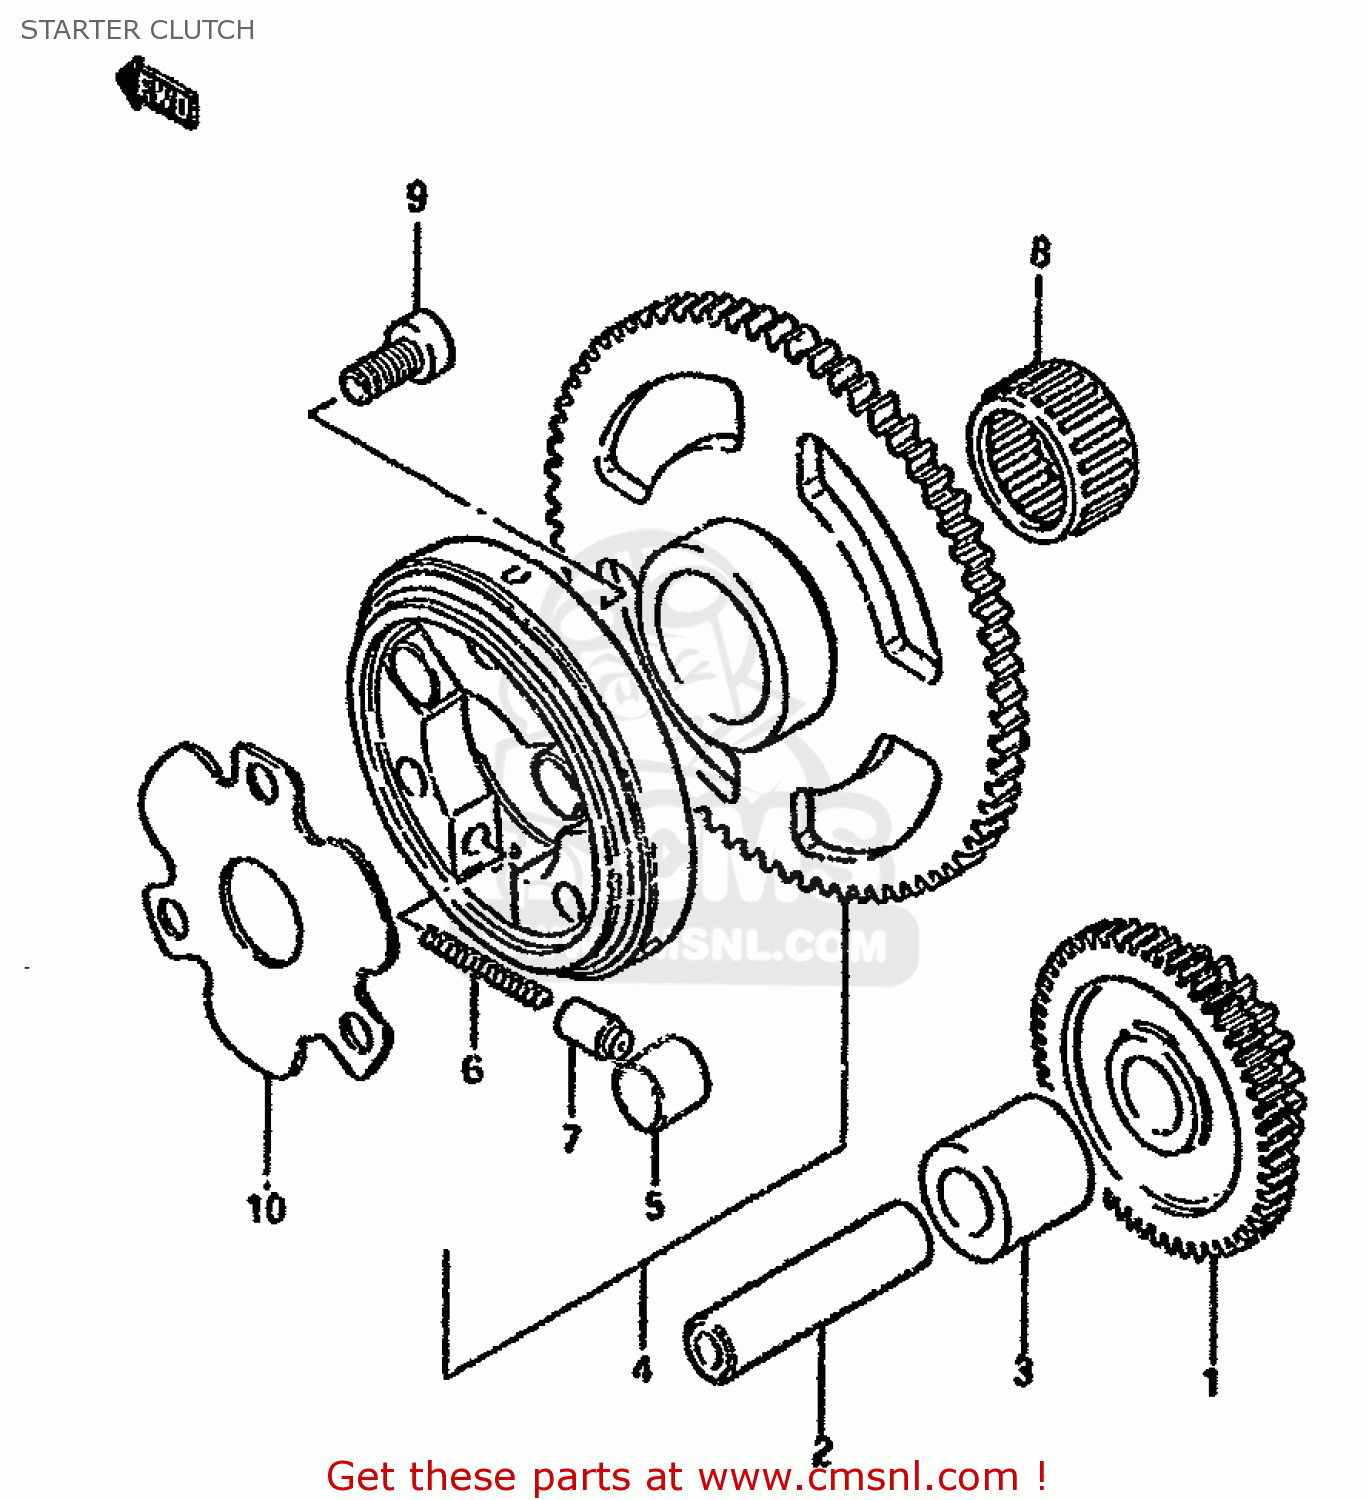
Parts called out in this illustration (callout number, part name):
1	GEAR,STARTER IDLER
2	PIN(7.4X13X56)
3	SPACER(13X19X19)
4	CLUTCH SET,STARTER
5	ROLLER(10X11)
6	SPRING
7	PIECE,STARTER CLUTCH PUSH
8	BEARING(22X28X16)
9	BOLT,OIL FILLE
10	SHIM,STARTER CLUTCH HUB
